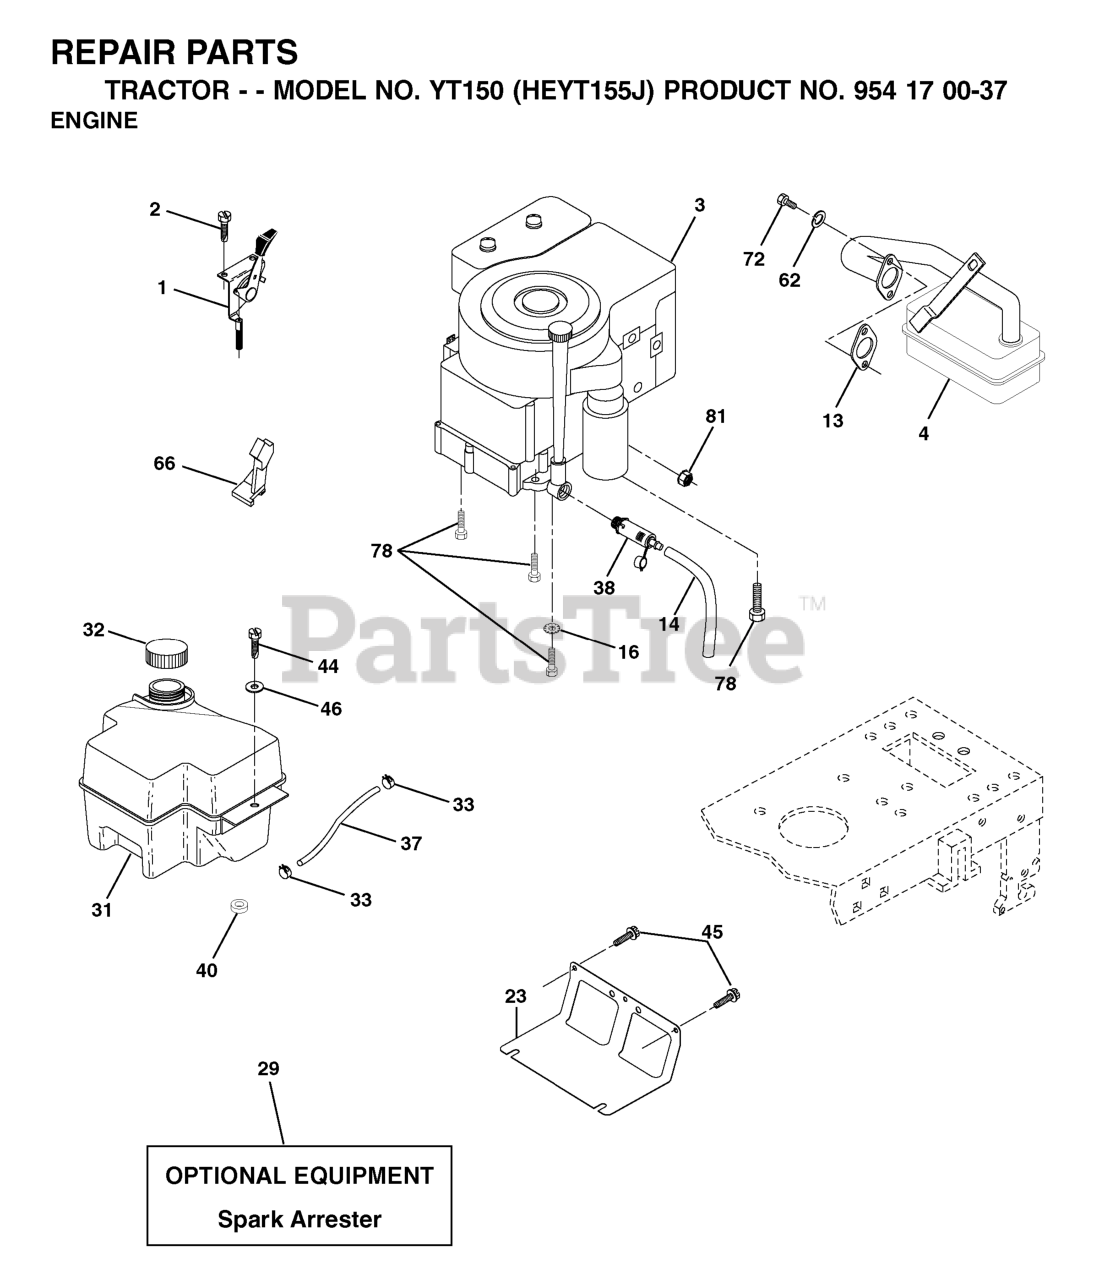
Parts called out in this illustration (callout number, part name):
1	THROTTLE.CONTROL.CABLE.BLACK
2	SCREW
4	MUFFLER.LT.BRIGGS.14HP.IC/OHV
13	REPL BY 532 27 22-93
14	TUBE, DRAIN OIL ASM.
16	LOCKWASHER
23	SHIELD.BROWNING.DBR.GUARD
29	KIT.SPARK ARRESTOR 794945 B&S
31	TANK, 2GAL
32	FUEL CAP
33	HOSE CLAMP
37	LINE.FUEL.20
38	PLUG, OIL DRAIN EASY
40	BUSHING.SNAP.NYL.BLK.
44	SCREW HEXWSHR 1/4-20X3/4
45	SCREW, 3/8-16X3/4
62	WASHER.LOCK.HVY.HLCL.SPR.5/16
66	STOP THROTTLE
72	SCREW
78	SCREW.3/8-16
81	NUT
